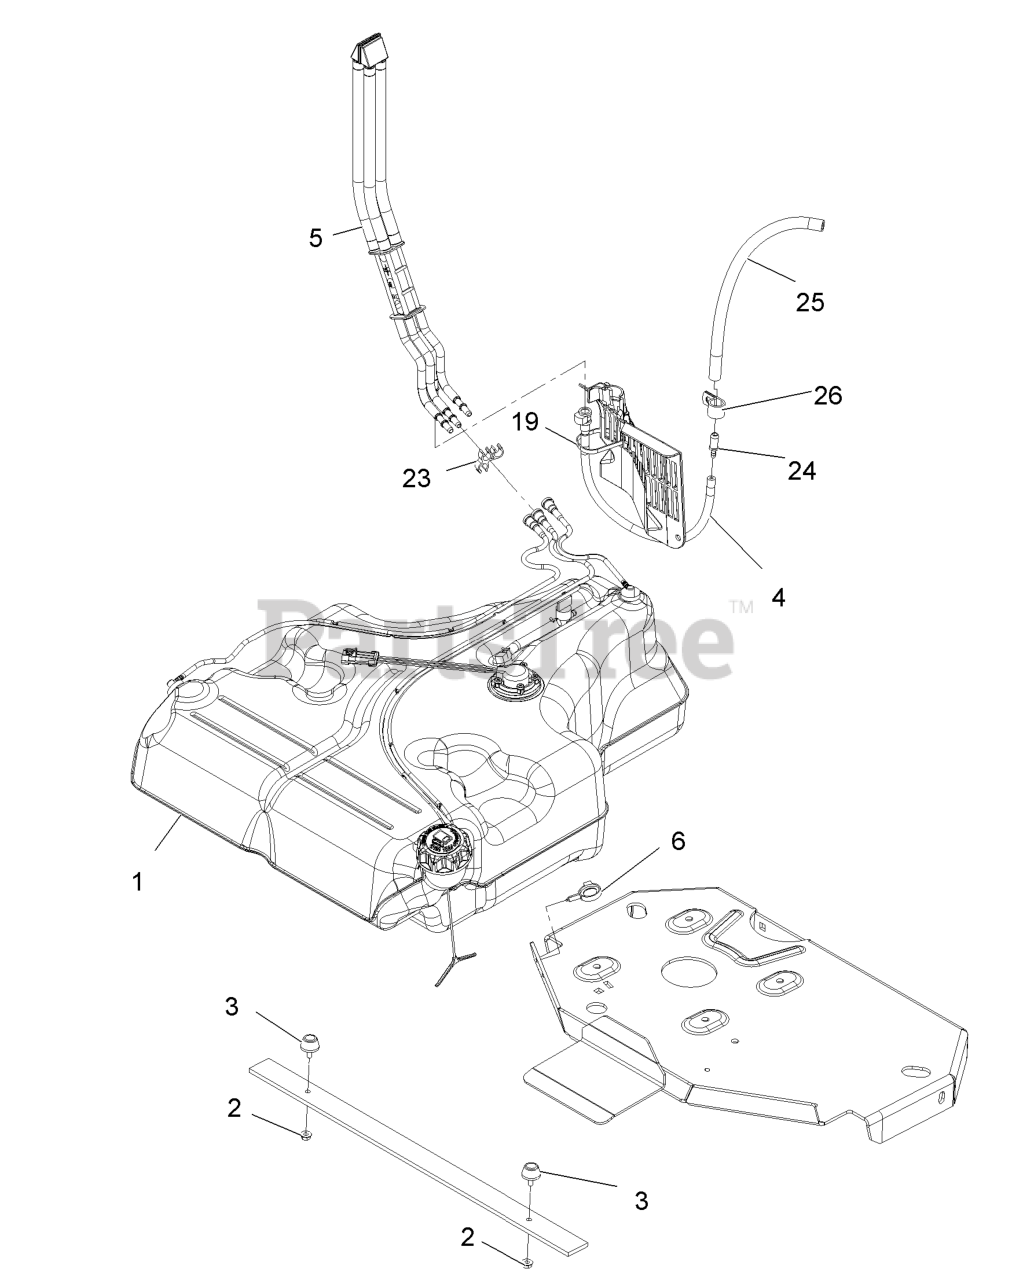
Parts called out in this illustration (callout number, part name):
3	BUMPER-RUBBER
4	HOSE ASM
5	FUEL MANIFOLD VENT ASM
6	CLAMP-HOSE
19	TIE-PLASTIC
23	CLIP-SPACER
24	FITTING-STRAIGHT
25	HOSE-FUEL
26	CLIP-LOOM
